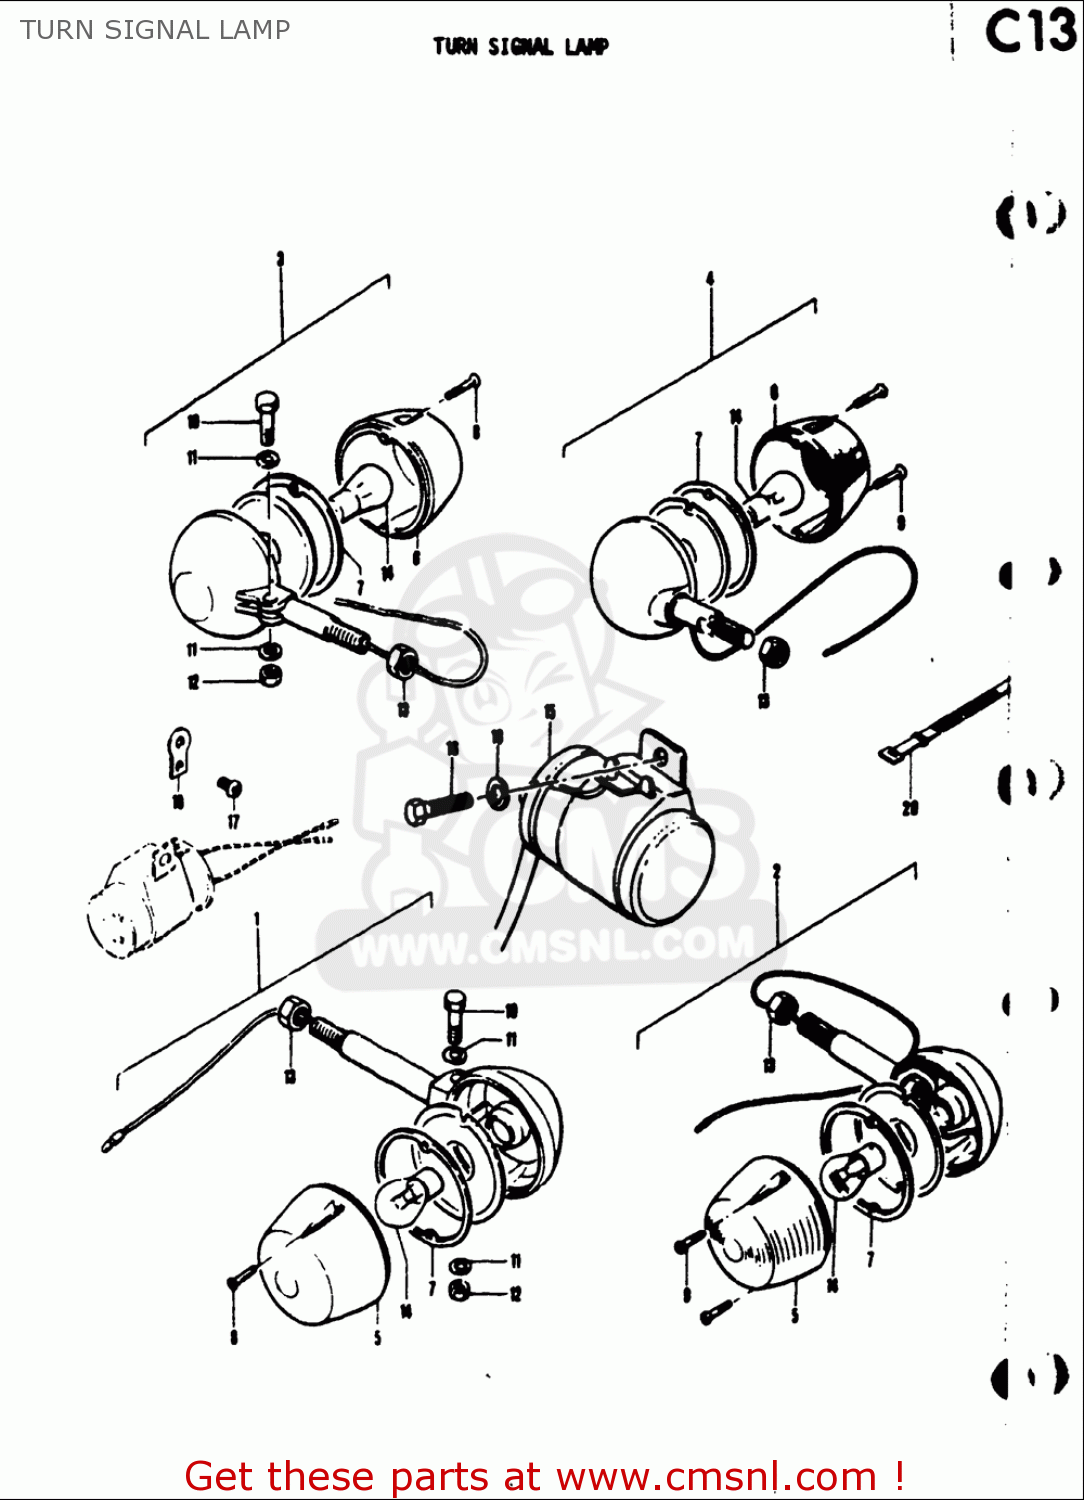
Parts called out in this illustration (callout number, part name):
2	LAMP ASSY,FR TURN SIGNAL
5	LENS,TURNSIGNAL
6	LENS,RR TURNSIGNAL LAMP
7	GASKET,TURNSIGNAL LENS (NAS)
8	SCREW
9	SCREW
11	WASHER
12	NUT
13	NUT
14	BULB(6V17W,STANLEY,A4513A)
15	RELAY ASSY,TURNSIGNAL
16	BOLT
17	SCREW
18	WASHER,LOCK
